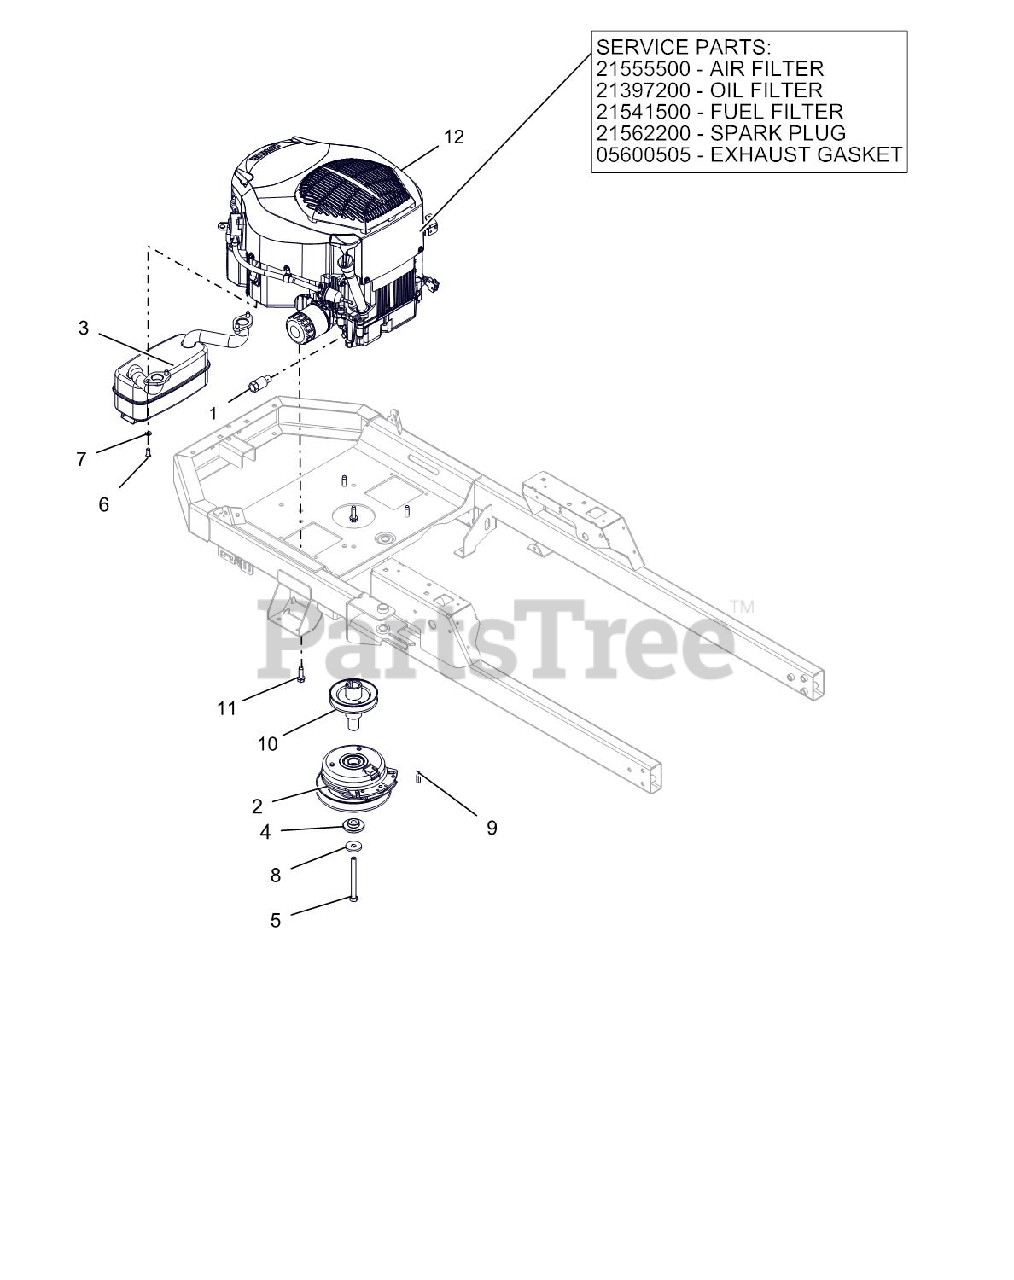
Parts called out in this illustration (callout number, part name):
1	DRAIN, OIL
2	CLUTCH,105FTLB MONOPOLE 6.83"
3	MUFFLER - KOHLER
4	BSHG-FLG .469X1.06X.574X2.0
5	BLT-HEX.438-20X4.5GR8YZ NYTORQ
6	SCR-CAP .31-18X.75 S/HD
7	@WSHR-LK .31X.078 REG YWZC
8	WASHER, 7/16" SPRING DISK
9	KEY-SQ .25 X 1.25 X .25 SAE
10	WLDMT, DRIVE SHEAVE-X
11	@SCR-TAP .38-16X1.25 HWH TR YZ
12	FILTER, OIL - KOH CV20
12	FILTER, FUEL
12	GASKET, MUFFLER COURAGE TWIN
12	AIR CLEANER, KOHLER
12	PLUG, SPARK (RFI)
12	ENGINE, KOHLER 22HP TWIN
